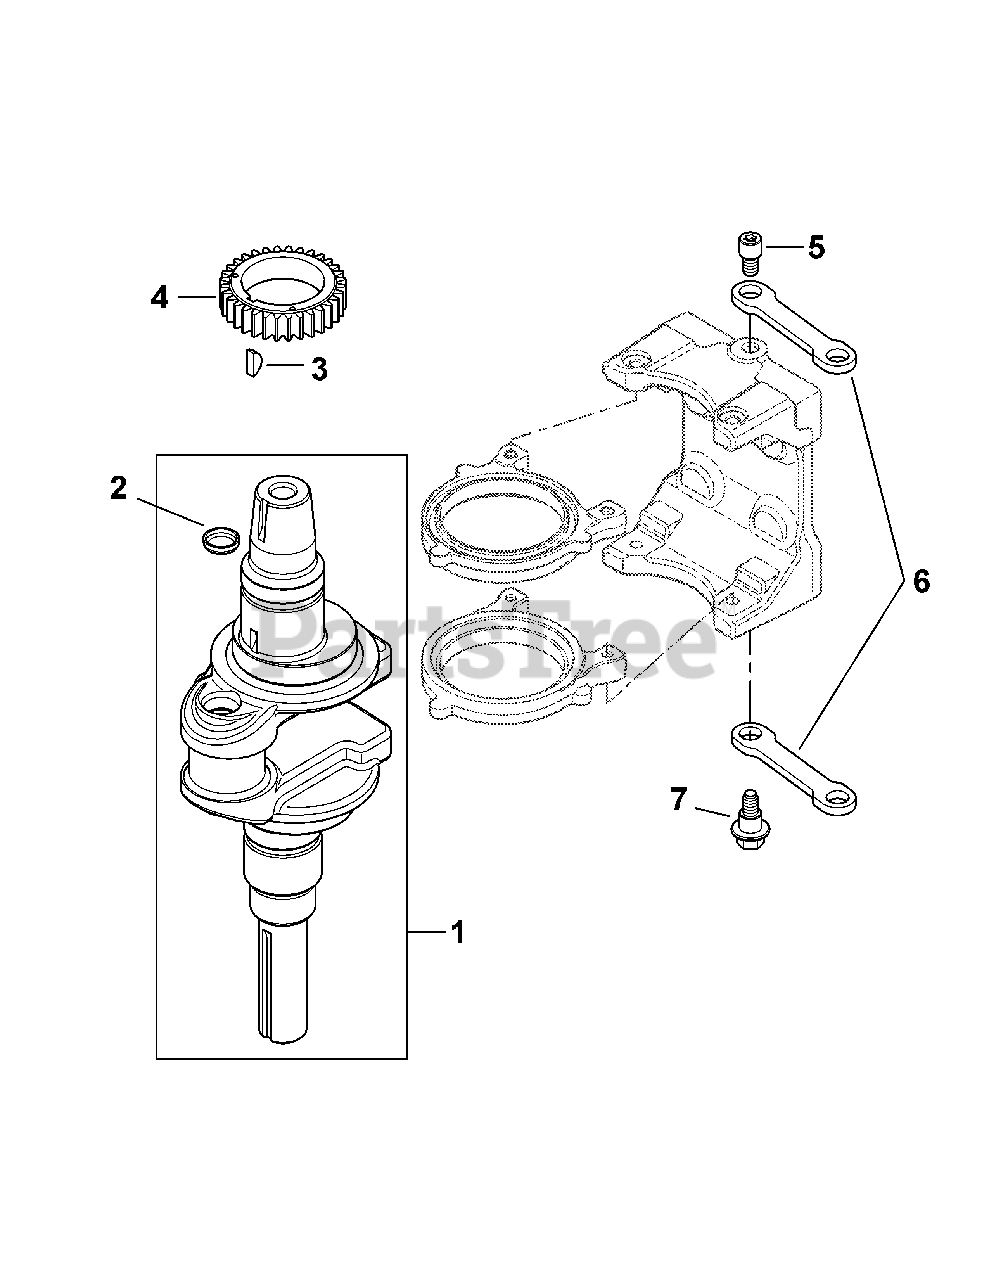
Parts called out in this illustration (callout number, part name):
1	Crankshaft Assembly Kit (Inc. 2)
3	Key, 3/16 X 5/8
4	Crankshaft Gear
5	Link Pivot Screw
6	Balance Weight Linkage
7	Shoulder Screw
